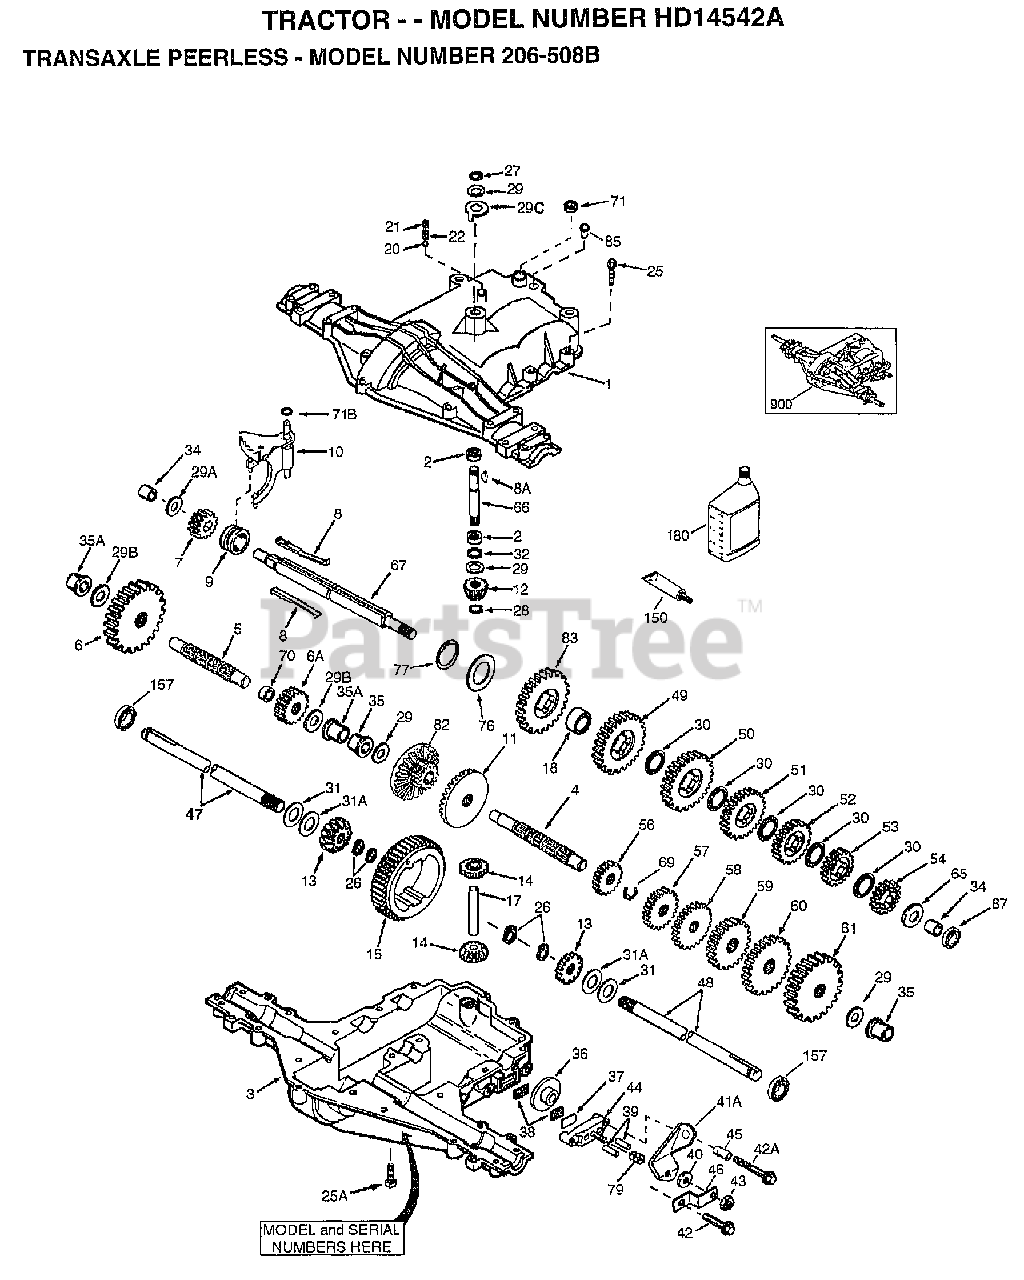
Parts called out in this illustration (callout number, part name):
1	TRANSAXLE COVER
2	NEEDLE BEARING 5/8" ID
3	TRANSAXLE CASE
4	COUNTERSHAFT
5	OUTPUT SHAFT
6	SPUR GEAR (38 TEETH)
6A	SPUR GEAR (15 TEETH)
7	SPUR GEAR (11 TEETH)
8A	KEY, WOODRUFF
9	COLLAR, SHIFTER
10	SHIFT ROD & FORK
11	BEVEL GEAR (30 TEETH)
12	INPUT BEVEL PINION (13TEETH)
13	BEVEL GEAR (13 TEETH)
14	BEVEL PINION (13 TEETH)
15	RING GEAR (43 TEETH)
18	SPACER, NEUTRAL
20	BALL STEEL, 5/16" DIA.
21	SCREW, 3/8-16 X 3/8"
25A	SCREW 1/4-20 X 1-3/8"
26	RING RETAINER
27	RING, RETAINER
28	RETAINING RING
29	WASHER THRUST
29B	WASHER THRUST
29C	P/N CONFLICT - CHECK WITH SUPPLIER
30	WASHER THRUST
31A	FLAT WASHER
32	OIL SEAL 5/8"
34	BUSHING 9/16"
35	FLANGED BUSHING 5/8" ID
35A	FLANGED BUSHING 3/4"
37	PLATE BRAKE PAD
41A	BRAKE LEVER
42A	SCREW, 1/4-20 X 2-1/4
43	LOCKNUT 5/16-24
44	HOLDER BRAKE PAD
46	BRKT BRAKE LEVER
49	SPUR GEAR (29 TEETH)
50	SPUR GEAR (27 TEETH)
51	SPUR GEAR (23 TEETH)
52	SPUR GEAR (19 TEETH)
53	SPUR GEAR (16 TEETH)
54	SPUR GEAR (15 TEETH)
56	SPUR GEAR (11 TEETH)
57	SPUR GEAR (13 TEETH)
58	SPUR GEAR (17 TEETH)
59	SPUR GEAR (21 TEETH)
60	SPUR GEAR (24 TEETH)
61	SPUR GEAR (25 TEETH)
66	INPUT SHAFT
67	SHIFTER & BRAKE SHAFT
69	RETAINING RING
70	SPACER .890
71	SEAL SQUARE CUT
76	WASHER, THRUST
77	INVERTED RETAINING RING
82	BEVEL & SPUR GEAR (30 & 13 TEETH)
83	SPUR GEAR (27 TEETH)
85	OIL FILL PLUG
87	OIL SEAL 9/16"
150	LIQUID GASKET RTV SILICONE
157	OIL SEAL 3/4"
180	GEAR OIL 80W90
900	REPLACEMENT TRANSAXLE
